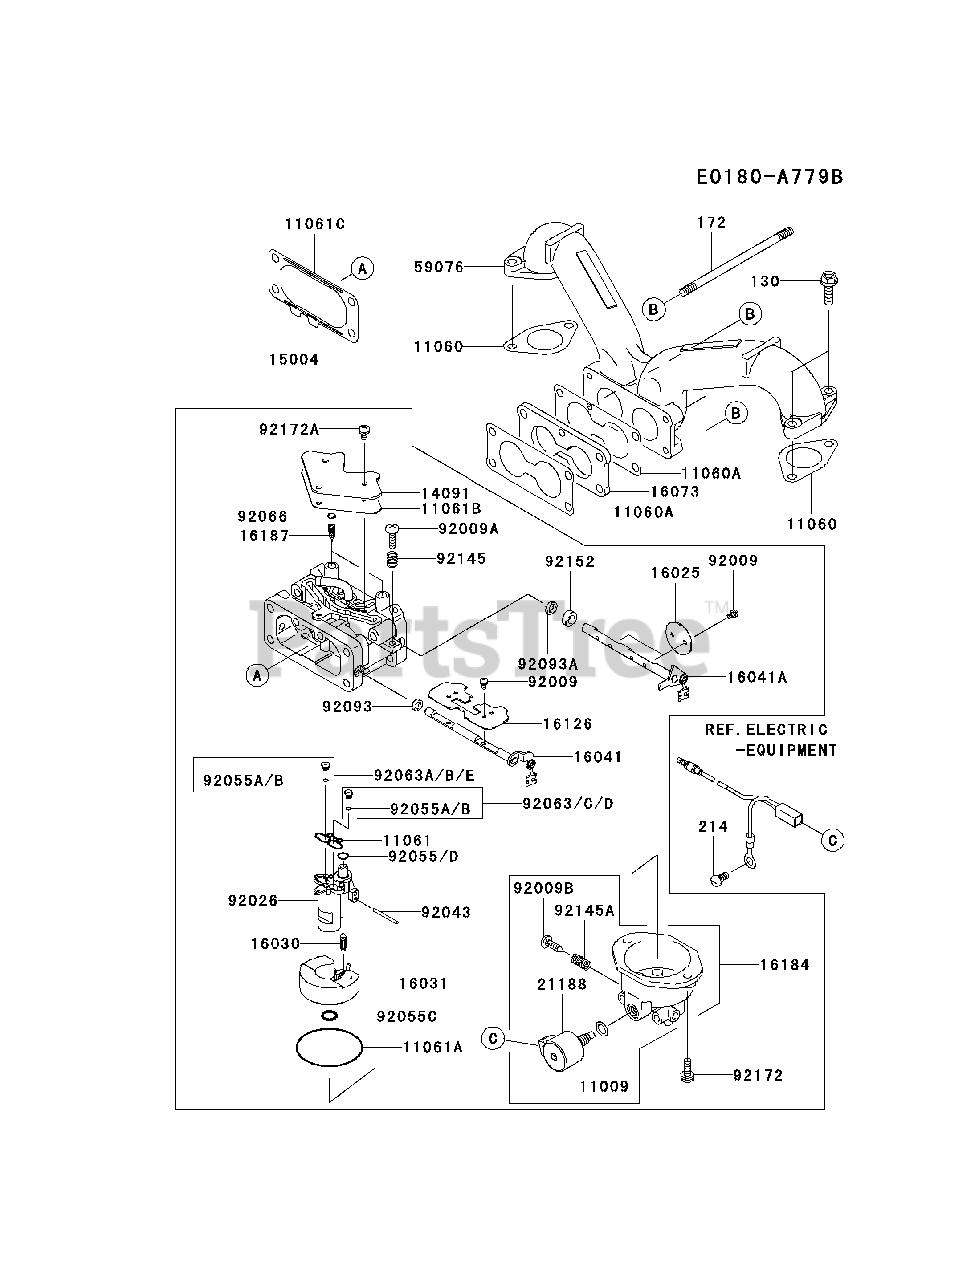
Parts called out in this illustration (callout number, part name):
130	BOLT-FLANGED,6X20
172	BOLT-STUD,6X105
214	SCREW-PAN+-,5X10
